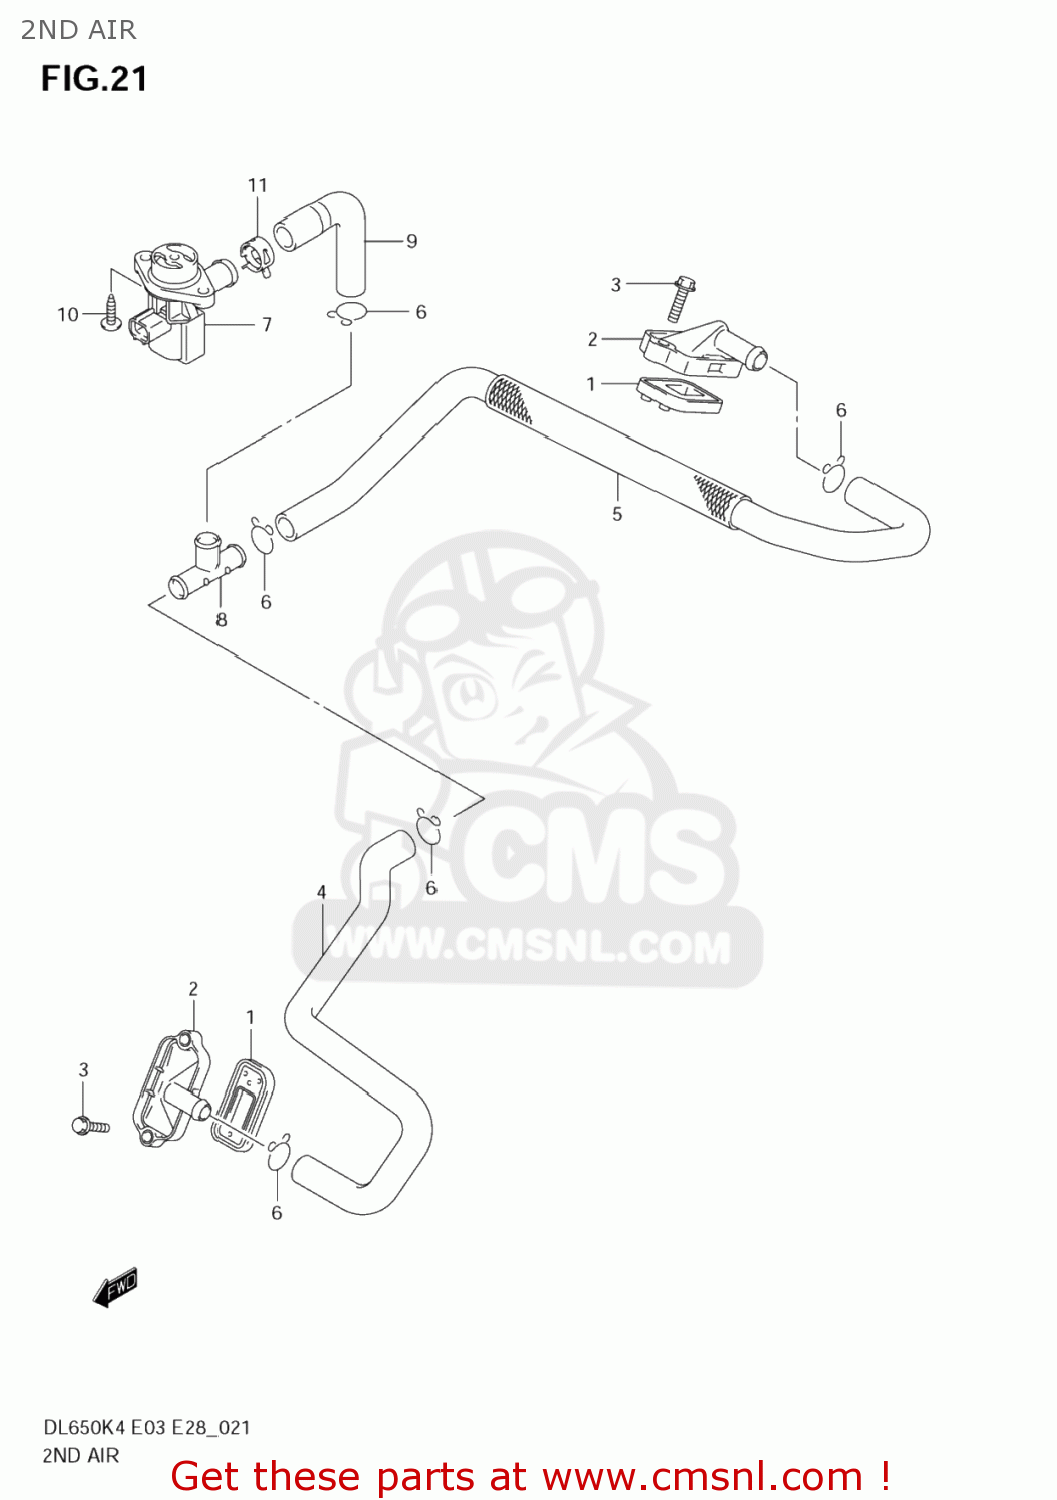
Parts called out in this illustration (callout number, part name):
1	VALVE ASSY,2ND AIR REED
2	COVER,2ND AIR
3	BOLT(6X20)
4	HOSE,2ND AIR VALVE FR
5	HOSE,2ND AIR VALVE RR
6	CLIP
7	VALVE ASSY,AIR CUT
8	JOINT
9	HOSE,2ND AIR VALVE
10	SCREW
11	CLAMP
